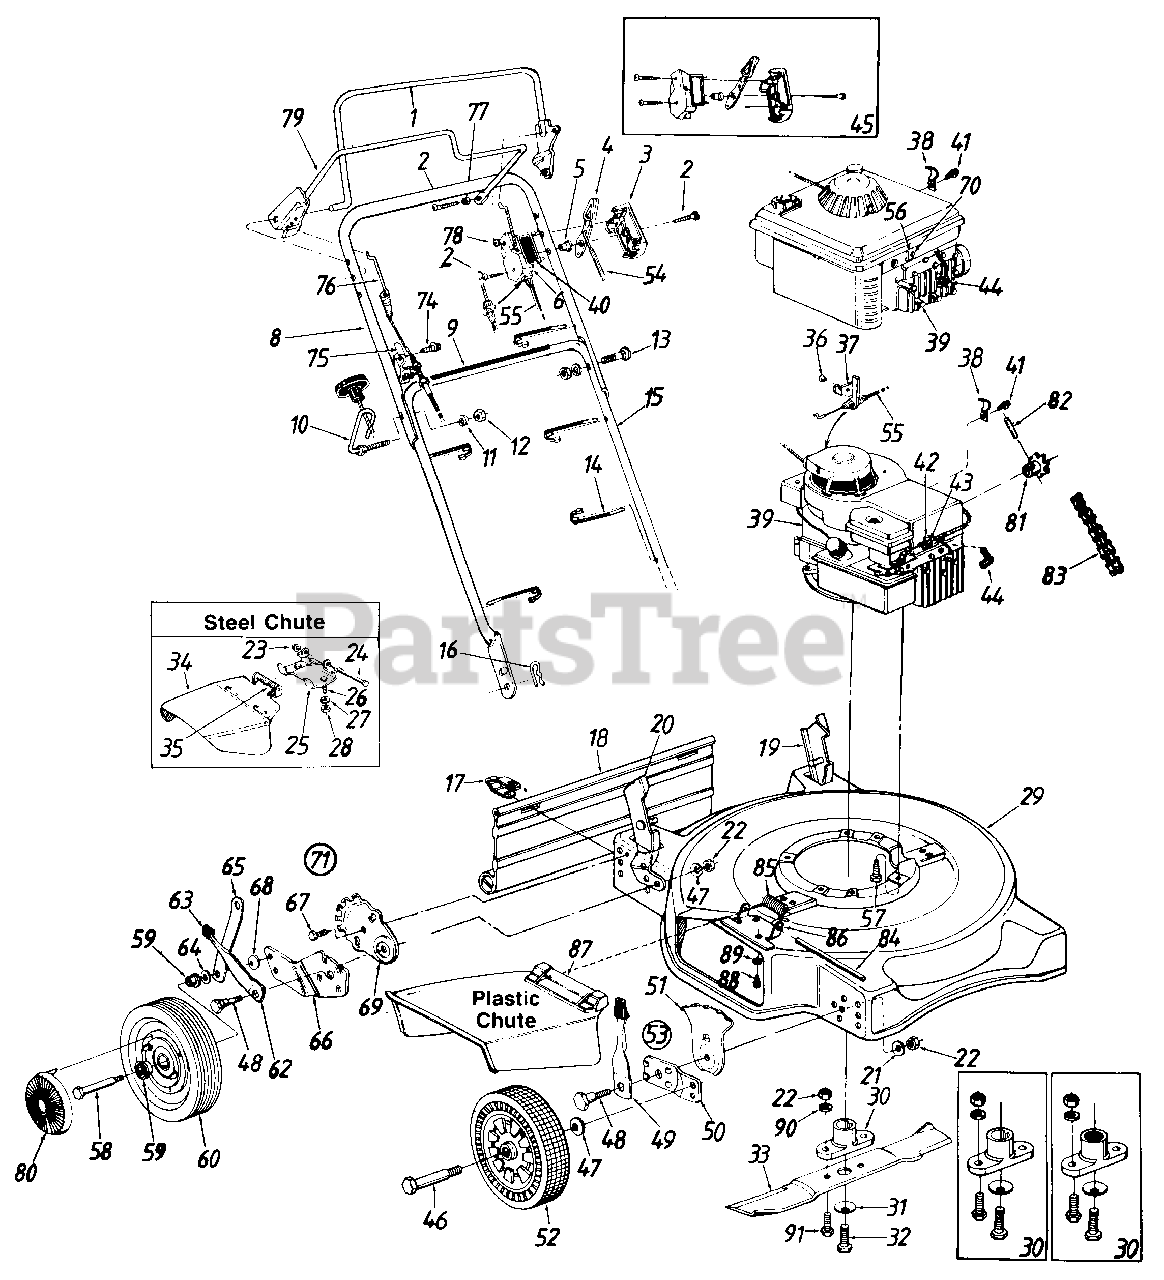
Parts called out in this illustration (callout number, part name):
1	Control Handle Ass'y.
2	Truss Mach. Scr. #12 x 1.5"
3	Control Panel Half
4	Throttle Control Lever
5	Control Disc Pin
6	Clutch Panel Half
8	Upper Handle (Painted)
9	Instruction Label-Handle
10	Rope Guide Bolt
11	L-Wash. 5/16" I.D.
12	Hex Nut 5/16-18 Thd.
13	Curved Carriage Bolt 5/16-18 x 1.38" Lg.
14	Cable Tie
15	Lower Handle (Painted)
16	Hairpin Cotter
17	Hinge Clip
18	Rear Flap
19	Handle Bracket Ass'y.-L.H.
20	Handle Bracket Ass'y.-R.H.
21	Bell-Wash. .39" I.D. x 1.38" O.D.
22	Hex Nut 3/8-16 Thd.
23	Push Cap 1/4" Rod
24	Pivot Pin
25	Adapter Plate
26	Hex Bolt 1/4-20 x .50" Lg.
27	L-Wash. 1/4" I.D.
28	Hex Nut 1/4-20 Thd.
29	22" Deck Ass'y.
30	Blade Adapter Kit
31	Bell-Wash. .39" I.D. x 1.12" O.D.
32	Hex Bolt 3/8-24 x 1.5" Lg.
33	22" Blade
34	Chute Deflector Ass y
35	Torsion Spring
36	Pop Rivet
37	Cable Bracket
38	Cable Clamp
39	Engine
40	Control Label-Throttle
41	Hex B-Tap Scr. #10 x .38"
42	Cable Clamp
43	Hex AB-Tap Scr. #8 x 38" Lg.
44	Spark Plug Boot
45	Kit-Control Housing Comp.
46	Front Axle Bolt
47	Bell-Wash. .400" I.D. x .88"
48	Shld. Bolt .50" Dia. x .357"
49	Spring Lever Ass'y. w/Knob
51	Height Adj. Plate
52	Wheel Ass'y. Comp.
53	Height Adj. Ass'y. Comp.-R.F.
54	Throttle Wire-53"
55	Control Cable-39"
56	Cable Clamp
57	Hex L-Wash. HD. Bolt 3/8-16 x 1.0" Lg.
58	Rear Axle Bolt
59	Fl. Ball Brg. 1/2" I.D.
60	Rear Wheel Ass'y. Comp.
62	Spring Lever
63	Spring Lever Knob
64	Fl-Wash. .531" I.D. x .93"
67	Hex AB-Tap 1/4-.62" Lg.
68	Bell-Wash. .380" I.D. x .88"
69	Index Plate
70	Hex B-Tap Scr. #10 x .62"
71	Rear Height Adj. Ass'y.-R.H.
74	Hex Wash. AB-Tap Scr. 5/16 x.75" Lg.
75	Cable Brkt.
76	Clutch Cable w/Spring-32" Lg.
77	Spacer .23" I.D. x .30" O.D.
78	Spr.-Wash. .206" I.D. x .448
79	S.P. Bail Ass'y.
80	Hub Cap
81	10 Tooth Sprocket Ass'y.
82	Spring Pin Spir. 1" Lg.
83	#48 Chain 1/2" Pitch x 50 Links-Endless
84	Hinge Pin
85	Torsion Spring
86	Adapter Plate
87	Chute Deflector Ass'y.
88	Hex Self-Tap Scr. 1/4-20 x .5" Lg.
89	Bell-Wash. 1/4" I.D.
90	L-Wash. 3/8" I.D.
91	Hex Bolt 3/8-16 x 1" Lg.
